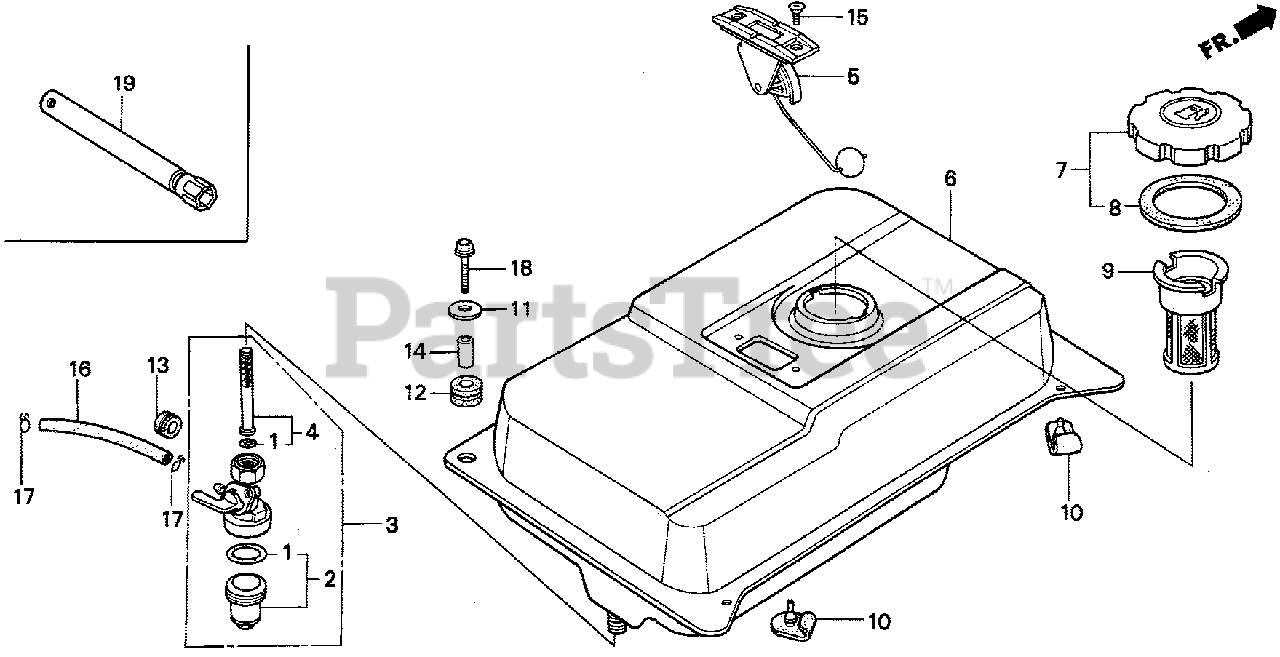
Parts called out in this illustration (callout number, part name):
1	GASKET SET, PETCOCK (CONTAINS 1 LARGE & 1 SMALL; USE AS NEEDED)
2	CUP, FUEL STRAINER
3	PETCOCK ASSY.
4	SCREEN SET
5	METER ASSY., FUEL
6	TANK, FUEL *T68* (TSURUI BLUE)
6	TANK, FUEL *Y131* (LIGHTNING YELLOW)
7	CAP, FUEL FILLER
8	GASKET, FUEL FILLER CAP
9	FILTER, FUEL
10	RUBBER, TANK MOUNTING
11	WASHER, FLAT (20MM)
12	RUBBER, CONTROL BOX
13	RUBBER, FUEL TUBE
13	RUBBER, FUEL
14	COLLAR, CONTROL BOX
15	SCREW, FLAT (5X10)
16	BULK HOSE, FUEL (4.5X3000) (4.5X150)
16	BULK HOSE, FUEL (4.5X3000) (4.5X260)
17	CLIP, TUBE (B8)
18	BOLT, FLANGE (6X20)
19	WRENCH, BOX (P21)
